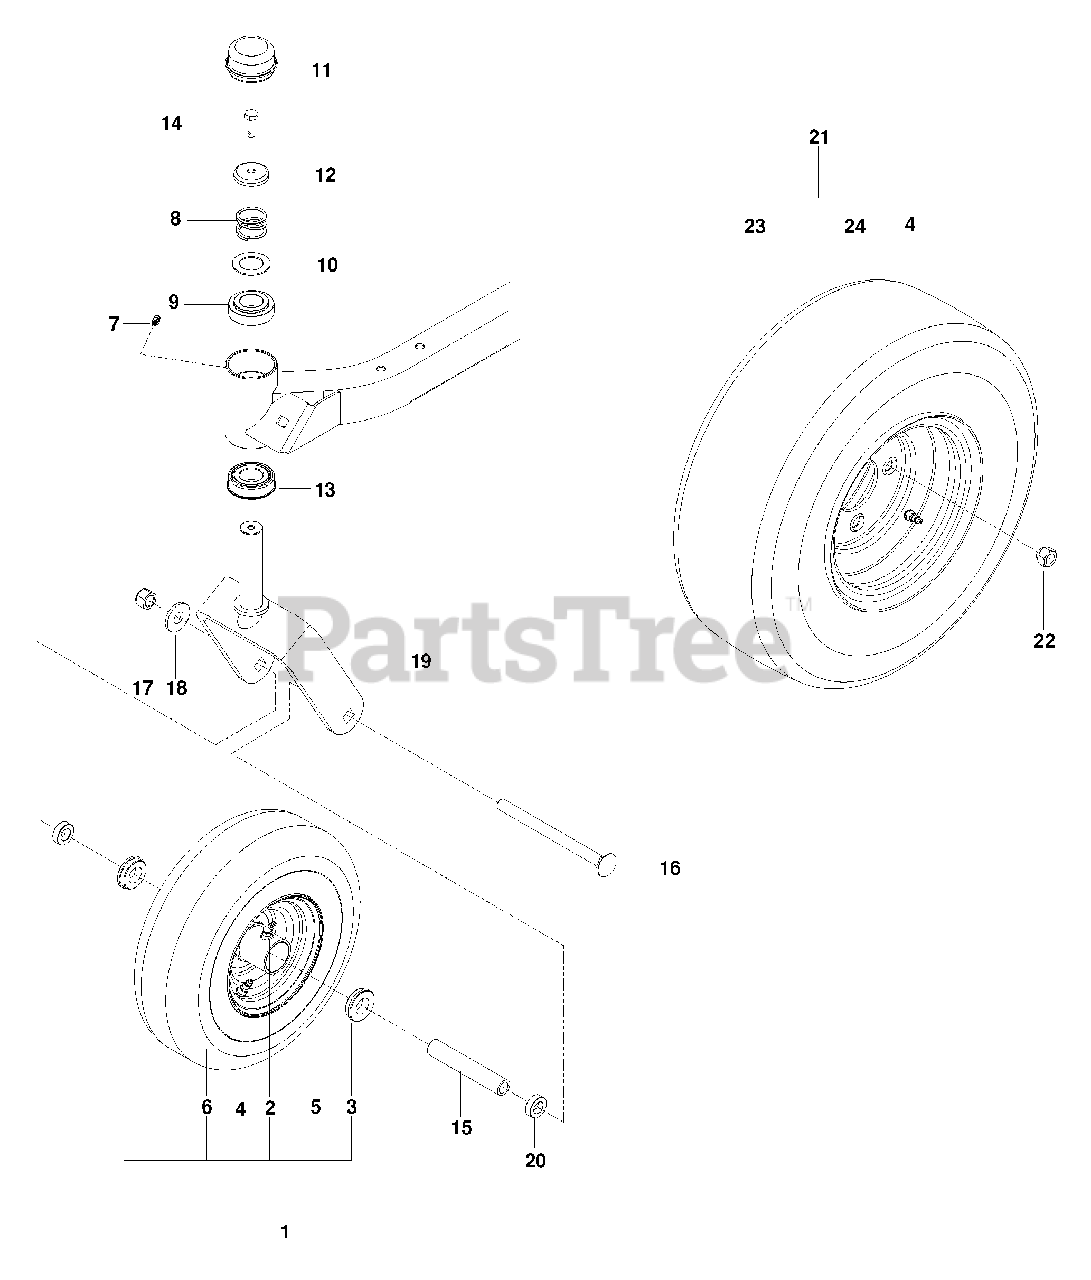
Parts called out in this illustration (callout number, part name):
1	CASTER TIRE ASSY
2	ZERK
3	BEARING, FLANGED
7	ZERK
8	SPRING, CASTER
9	BUSHING, CASTER
11	CAP, GREASE
12	PLUG, CASTER
13	BEARING, FLANGED
14	HHB 5/16-18 x 1 NYLOC
16	RHSNB 1/2-13 x 6 1/2
17	NUT 1/2 HEX NYLOC
18	WASHER 1/2 FLAT
19	YOKE, CASTER
20	SPACER 5/16
21	WHEEL ASSY REAR
22	NUT 1/2 LUG
23	TIRE 4 PLY 18 x 7.5 x 8
